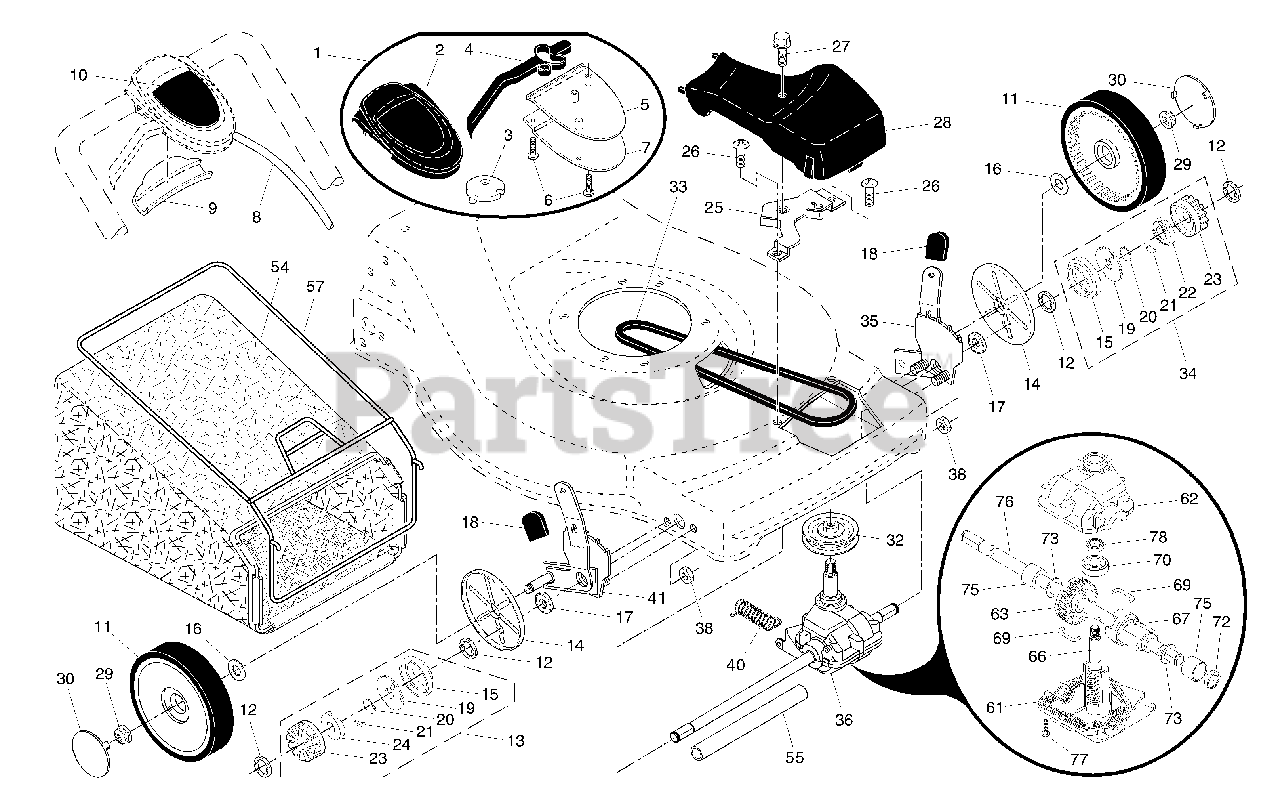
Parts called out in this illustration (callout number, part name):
1	Drive Control Assembly
2	Cover, Drive Control, Top
4	Lever, Drive Control
5	Cover, Drive Control, Bottom
6	Screw, Torx Head #8 x 5/8
7	Mounting Bracket, Drive Control
8	Cable, Drive Control
9	Cap, Drive Control, Bottom
10	Decal, Drive Control
11	Wheel & Tire Assembly
13	Pinion Assembly, RH
14	Dust Cover
15	Seal, Friction
16	Washer, Flat 3/8
17	Bearing, Wheel Adjuster
18	Selector Knob
19	Disc, Drive
20	Spring, Torsion
22	Retainer, Drive, LH
23	Gear, Pinion
24	Retainer, Drive, RH
25	Belt Guide Bracket
26	Screw
27	Pan Head Tapping Screw #10-24 x 2-3/4
28	Drive Cover
29	Locknut, Hex
30	Hubcap
32	Drive Pulley
34	Pinion Assembly, LH
35	Kit, Wheel Adjuster, LH
36	Gear Case Assembly, Complete
38	Locknut, Hex 1/4-20
40	Spring
41	Kit, Wheel Adjuster, RH
54	Grassbag Assembly
55	Driveshaft Cover
57	Frame, Grassbag
61	Case, Lower Use Dow Corning #709 to reseal Gear Case Halves.
62	Case, Upper Use Dow Corning #709 to reseal Gear Case Halves.
63	Gear, 27 Teeth
66	Shaft, Input
69	Wire, Formed
70	Bearing, Ball
72	Seal, Output Shaft
76	Shaft, Output
78	Seal, Input Shaft
